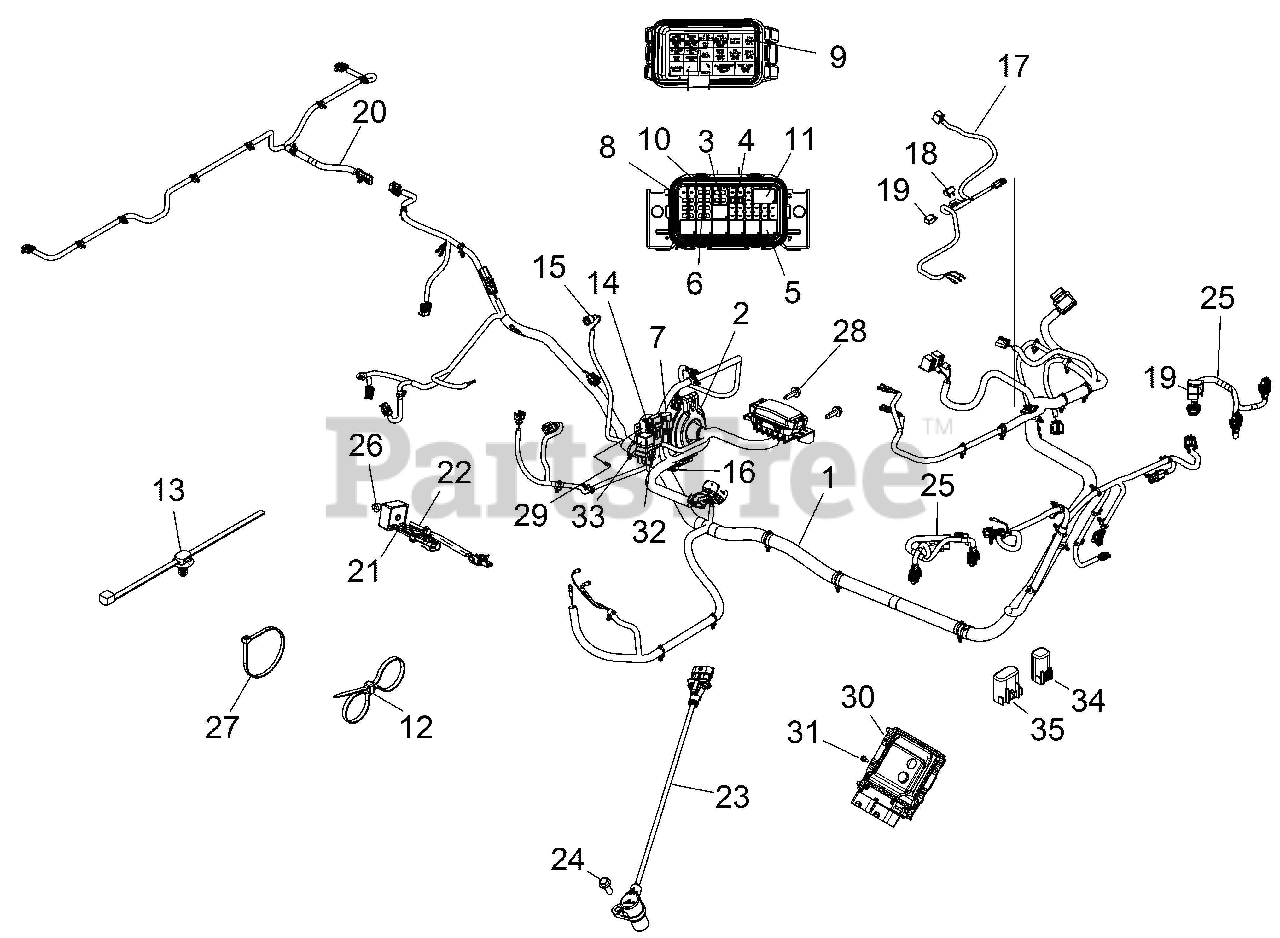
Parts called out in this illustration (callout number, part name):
1	HARNESS-CHASSIS,DSL,EPS
1	KIT, FUSIBLE LINK, 2MM
1	KIT, FUSIBLE LINK, 1MM
1	KIT, FUSIBLE LINK, .8MM
2	GROMMET-CHASSIS HARNESS
3	FUSE-5A,MINI BLADE
4	BREAKER-CIRCUIT,20 AMP
5	RELAY-SPST,SERIES 303,SEALED
6	FUSE, 20 AMP, PARK
7	COVER-DIAGNOSTIC,W/CLIP
8	FUSE,MAIN,30 AMP,(10)
9	DECAL, FUSE BLOCK
10	FUSE, MINI BLADE, 15 AMP
11	RELAY-SPDT,SERIES 301,SEALED
12	CABLE TIE
13	CLIP-ROUTING
14	CLIP, X-MAS-TREE
15	BOOT, OIL PRESSURE SWITCH
16	TVS, 30VOLT
17	HARNESS-BOX,LIFT
18	BREAKER-CIRCUIT,20 AMP,SEALED
19	RELAY-MICRO,SPST,35A,SEALED
20	HARNESS-BOX-ARIENS SPLY
21	RELAY, SOLID STATE,9A,LONG LD
22	BOLT-M6X1.0X35,HXFLG/SH-OLV D
23	SENSOR-CRANK POSITION
25	HARNESS-HEADLIGHT,ARIENS
26	NUT-M6X1.0,FLG-NYLOC-OLIVE D
27	CABLE TIE (10)
28	SCR-M6X1.0X20,HXHD,FLG,TDFM,BL
29	CLIP, PLASTIC DART, NYLON
30	SERVICE ECU, ALL MY11 800 DOM
31	SCR-#10X1/2-HI/LO-PN-T25,TRX-M
32	FUSE-80 AMP
33	RELAY-GLOW PLUG
34	CONNECTOR-CAP,EPS SIGNAL
35	CONNECTOR-CAP,EPS POWER
